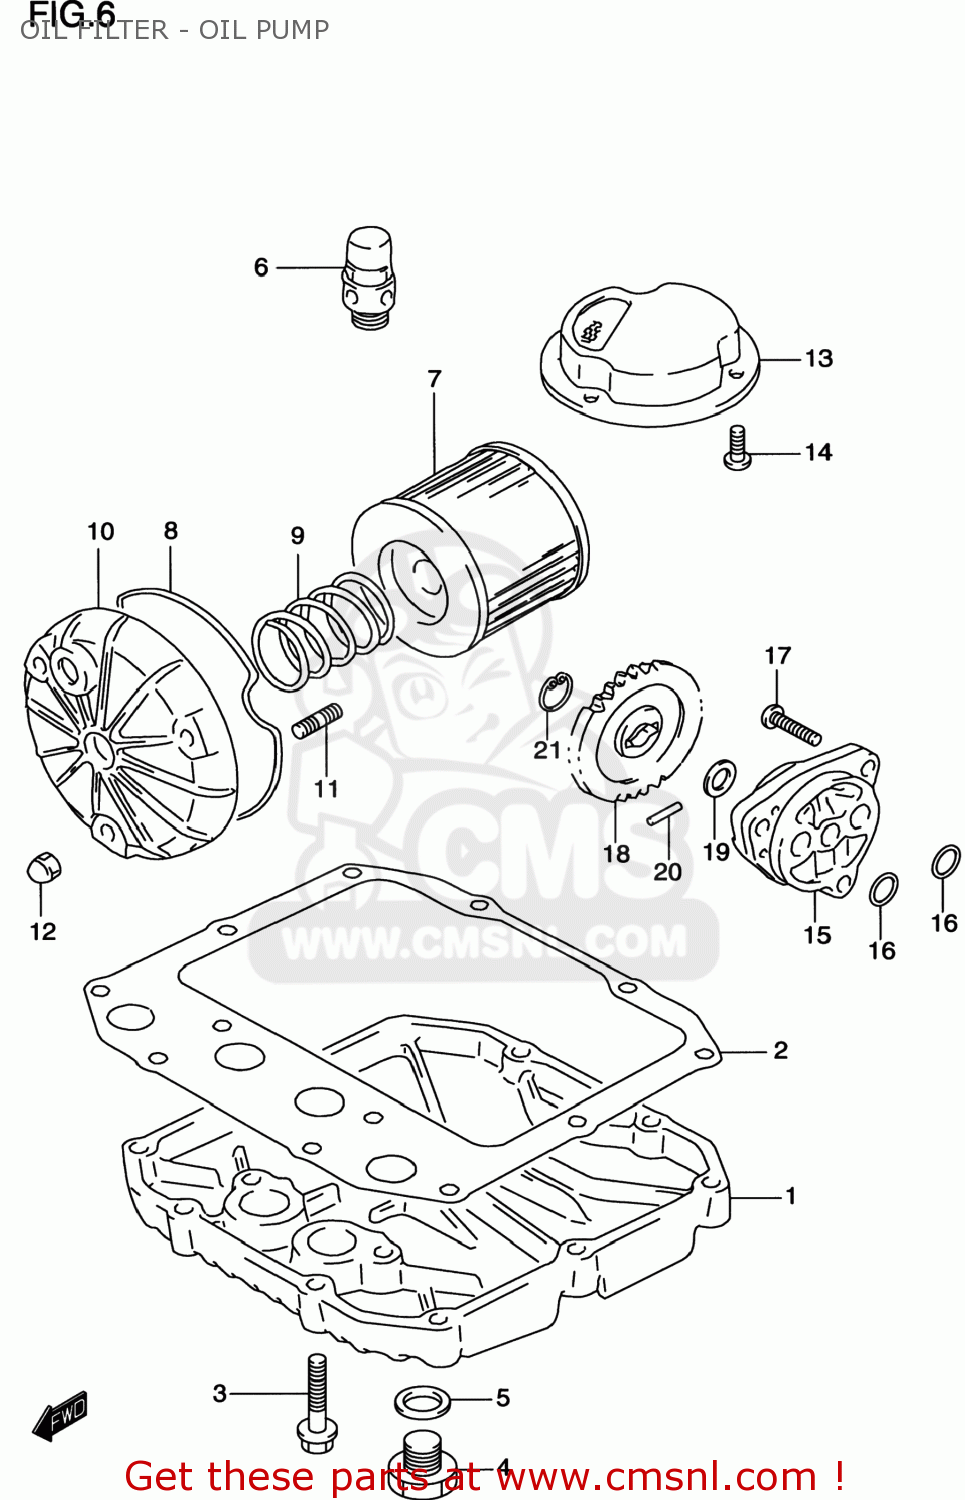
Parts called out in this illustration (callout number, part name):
1	PAN,OIL
2	GASKET,OIL PAN(ASB) (NAS)
3	BOLT
4	PLUG
5	GASKET(13.8X18.8X4.8) (NAS)
6	REGULATOR ASSEMBLY,ENGINE
7	FILTER ASSY,ENGINE OIL
8	O RING,OIL FILTER CHAMBER CAP
9	SPRING
10	CAP,OIL FILTER
11	STUD 6X20
12	NUT
13	STRAINER,ENGINE OIL
14	BOLT
15	PUMP ASSY,ENGINE OIL
16	O RING(D:1.9,ID:13)
17	SCREW
18	GEAR,OIL PUMP DRIVEN
19	SHIM(10X18X0.5)
20	PIN(4X15.8)
21	CIRCLIP,10MM
